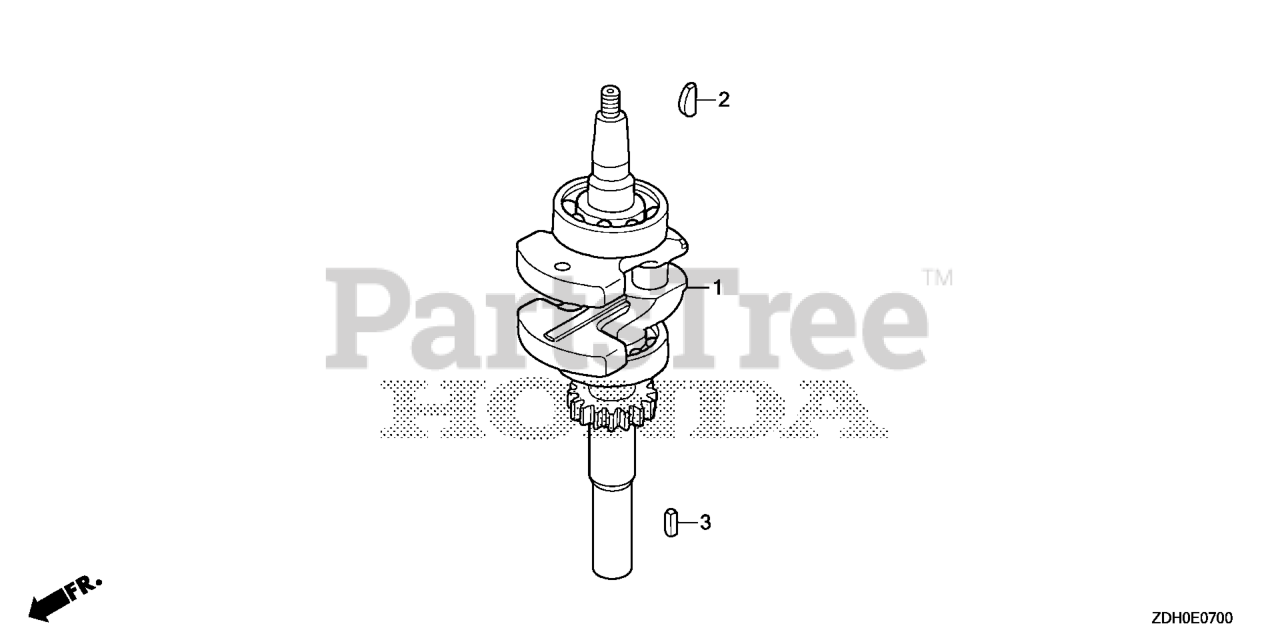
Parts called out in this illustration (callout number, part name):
1	CRANKSHAFT
2	KEY, SPECIAL
3	KEY (5MM)
